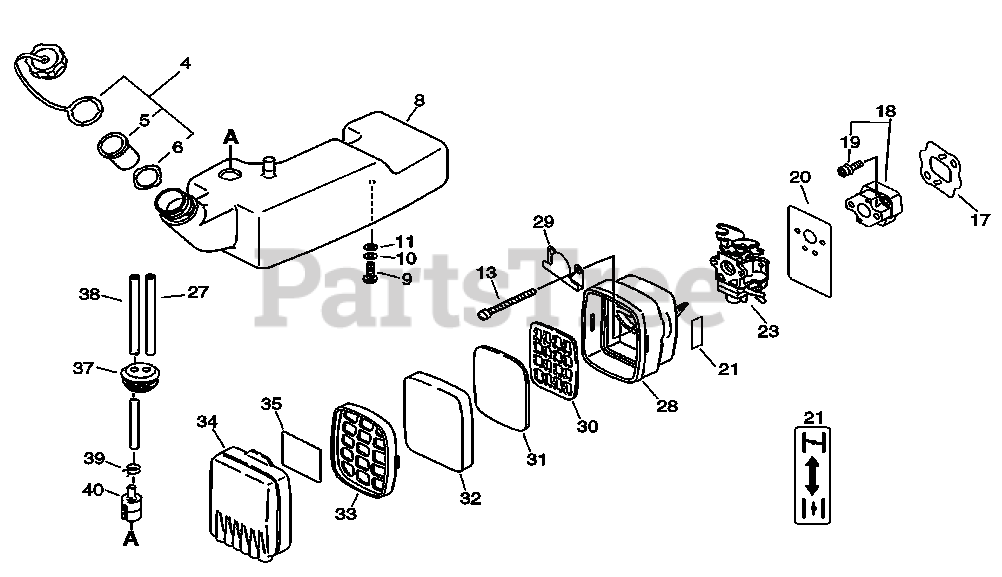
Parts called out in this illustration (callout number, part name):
4	CAP ASSY, FUEL
5	CAP, VENT
6	GASKET, FUEL CAP
8	TANK, FUEL
9	SCREW 6×14
10	WASHER, SPRING 6
11	WASHER 6.5×18×1.6
13	SCREW 5×60
17	GASKET, INTAKE
18	INSULATOR KIT, INTAKE
19	BOLT 5×30
20	GASKET, INTAKE
21	LABEL, CHOKE
23	CARBURETOR
27	PIPE, FUEL RETURN 3×6×145
28	CASE ASSY, AIR FILTER
29	PLATE, PREVENT
30	GRID, AIR FILTER
31	FILTER, AIR
32	PRE-FILTER, FOAM
33	GRID, PRE-FILTER
34	COVER, AIR FILTER
35	LABEL, AIR FILTER
37	GROMMET, FUEL
38	PIPE, FUEL 3×6×280 MM
39	CLIP Ø6.5 MM
40	FILTER, FUEL
